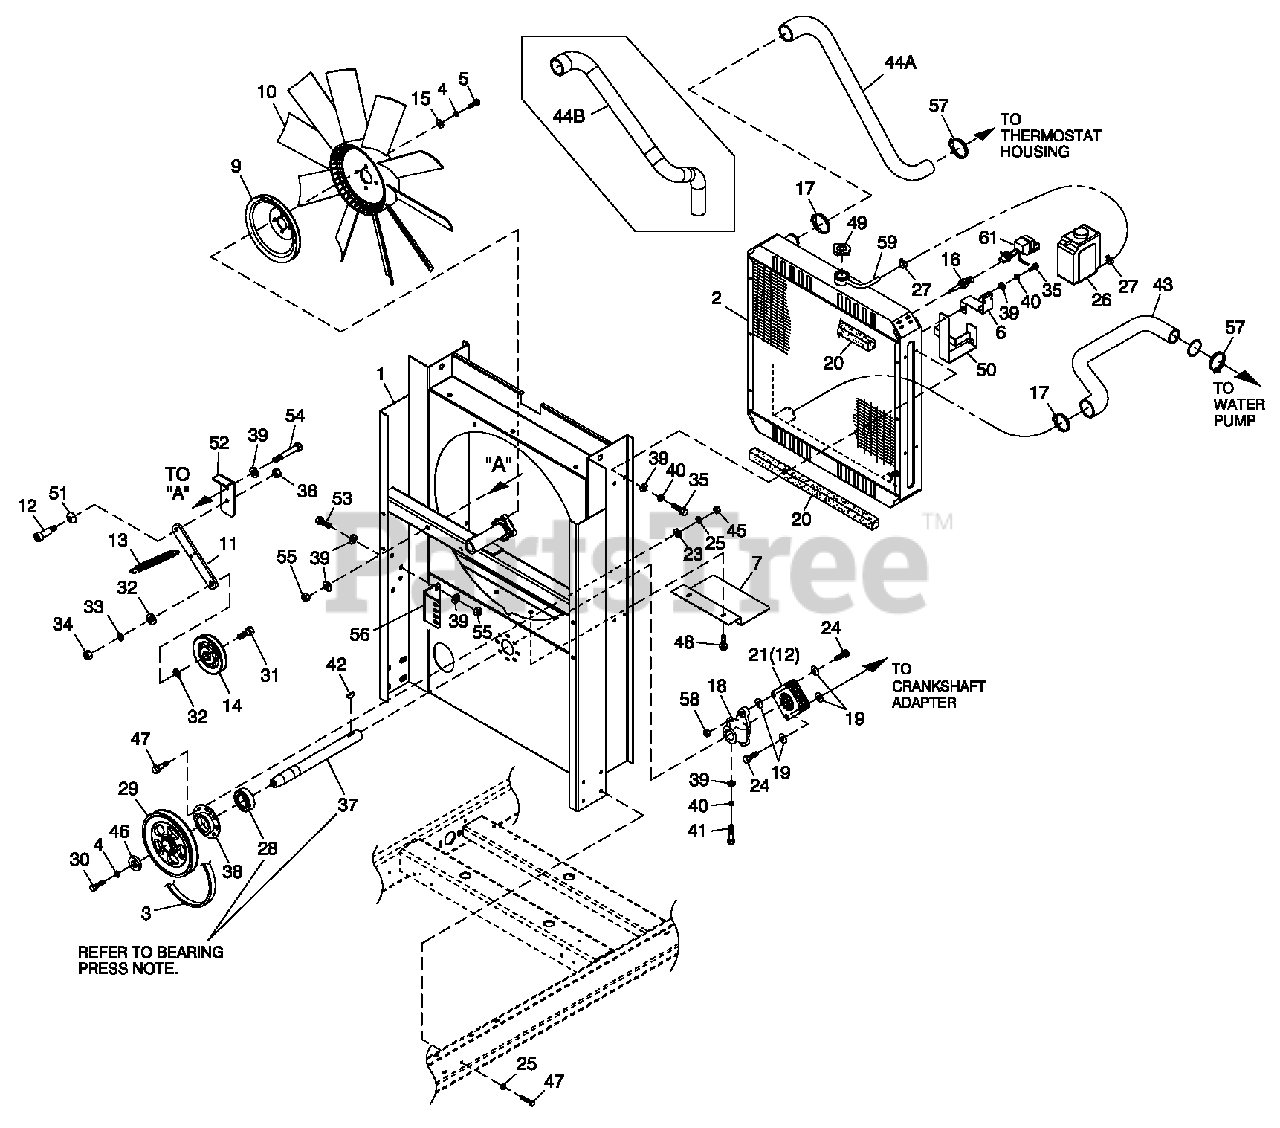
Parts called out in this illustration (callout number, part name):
1	WELDMENT RADIATOR SUPPORT C2
2	RADIATOR 598 X 568 X 49 CPL RH
3	V-BELT 31/64" X 57-3/8"
4	WASHER LOCK M10
5	SCREW HHC M10-1.5 X 30 G10.9
6	BRACKET, SIGNAL CONDITIONER (USED ONLY WITH QTAPRODUCT)
7	SHIELD RADIATOR C4
9	PULLEY FANV-GROOVE9"
10	FAN COOL 22" DIA 10 BLADE LH
11	FLATTENSIONER ARM
12	SHOULDER BOLT 3/8X 1/2"
13	SPRING TENSION CPL
14	PULLEY V-BELT 4" FLANGED
15	WASHER FLAT 3/8-M10 ZINC
16	PROBE COOLANT LEVEL 3/8 NPTF (USE W ITH HARNESS P/N 0G4882)
17	CLAMP HOSE #28 1.32-225
18	HUB FLEX PLATE
19	WASHER FLEX (THIN)
20	TAPE FOAM 1 X 1 (26.75" LG)
21	DISK FLEX
23	WASHER FLAT 1/4-M6 ZINC
24	SCREW HHC 5/16-24 X 1.124
25	WASHER LOCK M6-1/4
26	TANK COOLANTRECOVERY
27	CLAMP HOSE BAND 1/4
28	BEARING #6205 2NSE C3 ESRI2 S
29	PULLEY 4.5" DIA MACHINED
30	SCREW HHC M10-1.5X 30 G8.8
31	SCREW HHC 1/2-13 X 2" G8
32	WASHER FLAT 1/2 ZINC
33	WASHER LOCK 1/2
34	NUT HEX 1/2-13 STEEL
35	SCREW HHFC M8-125 X 2 0W/M6
36	NUT HEX LOCK 5/16-18 NY INS SS
37	SHAFT FAN DRVE
38	RETAINER BEARING
39	WASHER FLAT 5/16-M8 ZINC
40	WASHER LOCK M8-5/16
41	SCREW HHC M8-1.25 X 45 C8.8
42	KEY WOODRUFF 4X 19D
43	HOSE LOWER RADIATOR G2
44	HOSE UPPER RADIATOR G2
45	NUT HEX M6X 1.0 G8 YEL CHR
46	SPACER .5X 1.5 X .2 5 STL/ZINC
47	SCREW HHFC M6-10 X 2 0 G8.8
48	SCREW THF M6-1 X 16 N WAZ/JS
49	CAP RADIATOR 13 PS I
50	BRACKET COOLANT TANK
51	WASHER BELLEVILLE .75X.38X.028
52	TENSIONER ARM SUPPORT BENT 90
53	SCREW HHC M8-1.25 X 20 C8.8
54	SCREW HHC M8-1.25 X 75 C8.8
55	NUT HEX LOCK M8-1.25 NY INS
56	BRACKET TENSIONER SPRING
57	CLAMP HOSE #24 B1.06-2.00
58	NUT HEX LOCK 5/16-24 NY INS
59	HOSE 9/32 ID(27"LG)
61	ASSY PCB LCL SENSOR (USE WITH I/N 16, P/N 0H1827 0NLY)
